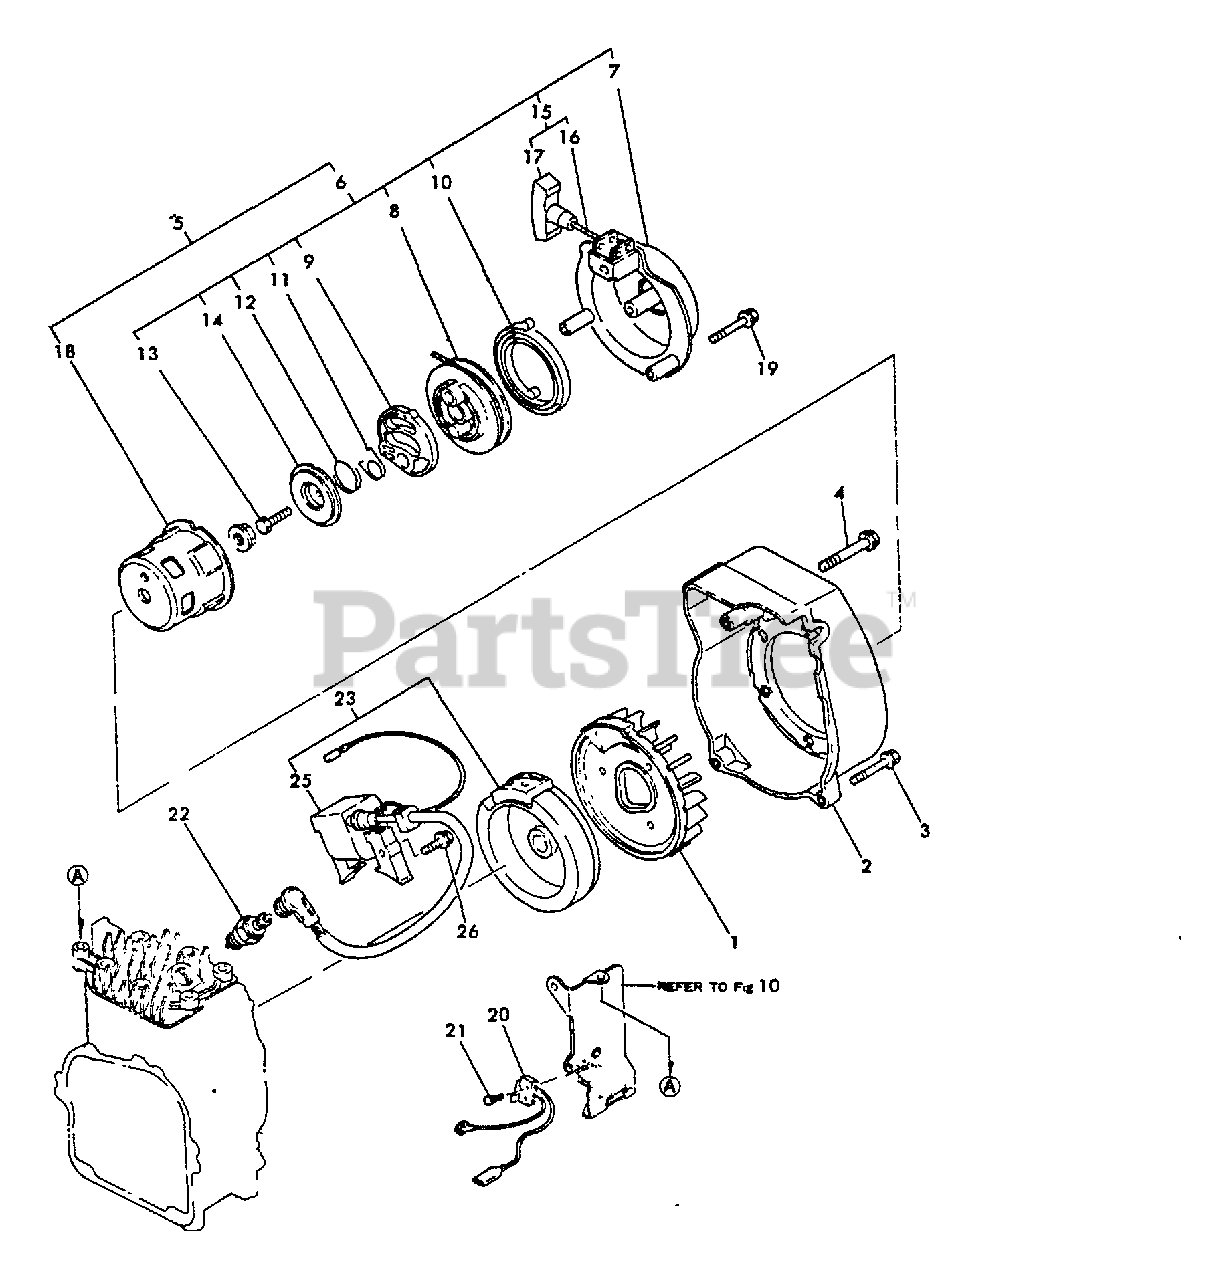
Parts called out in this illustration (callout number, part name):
1	FAN
2	COVER, FAN
3	BOLT - 6×30
4	BOLT - 6×40
5	STARTER ASSY
6	RECOIL ASSY
7	STARTER CASE ASSY
8	PULLEY
9	RATCHET
10	SPRING
11	SPRING, RETURN
12	SPRING, FRICTION
13	BOLT
14	PLATE, FRICTION
15	STARTER ROPE ASSY
16	ROPE, STARTER
17	KNOB, STARTER
18	PULLEY, STARTER
19	BOLT - 6×35 -- PLATED
20	SWITCH, STOP
21	SCREW - 2×10 -- TAPPING
22	SPARK PLUG - BPM-8Y
23	FLYWHEEL MAGNETO
25	IGNITER
26	BOLT - 6×20
